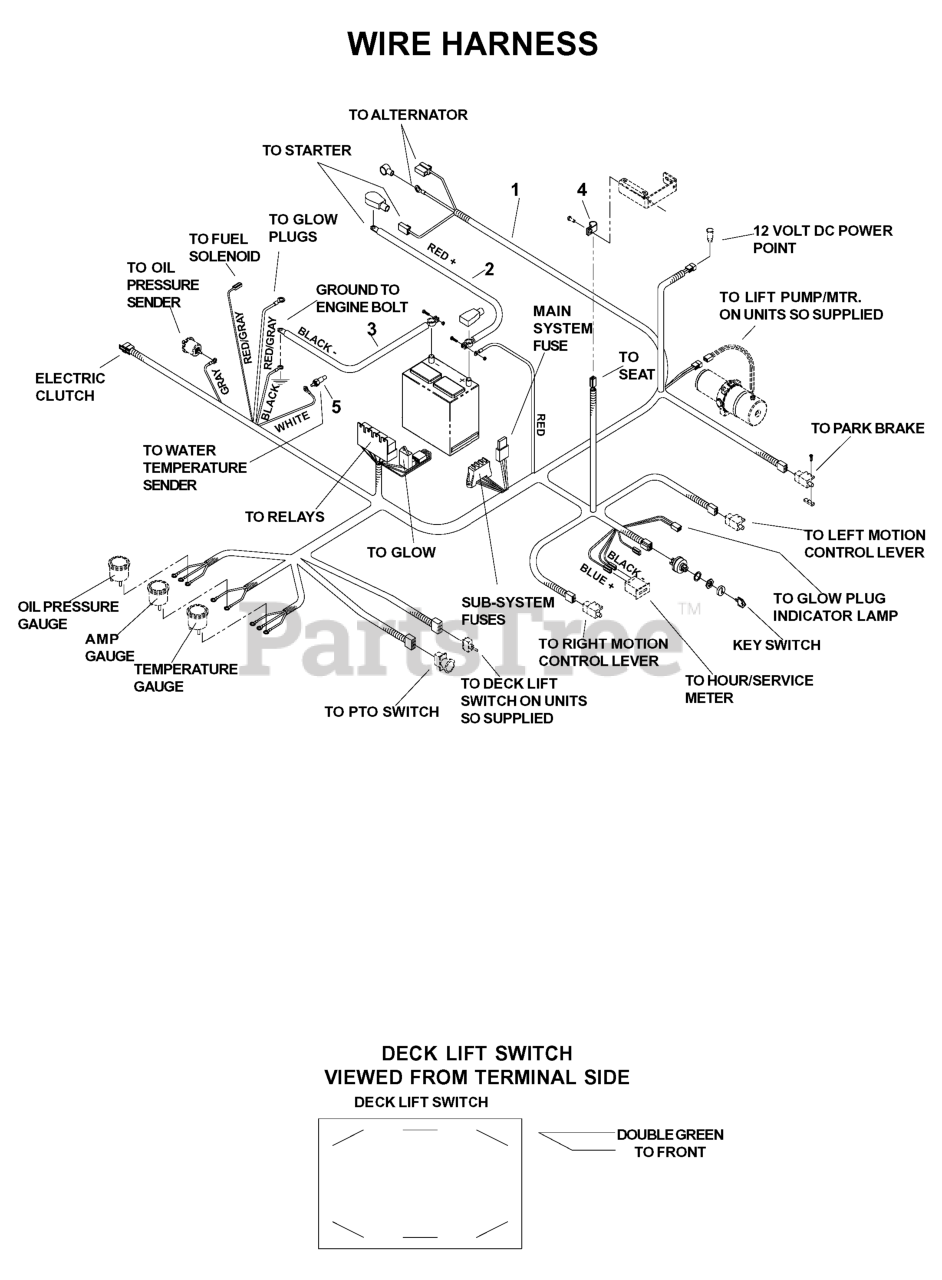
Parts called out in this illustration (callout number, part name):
1	HARNESS, ENG - B&SD DIESEL
2	CABLE, POS.
3	CABLE, NEG.
5	SENDER,TEMP
